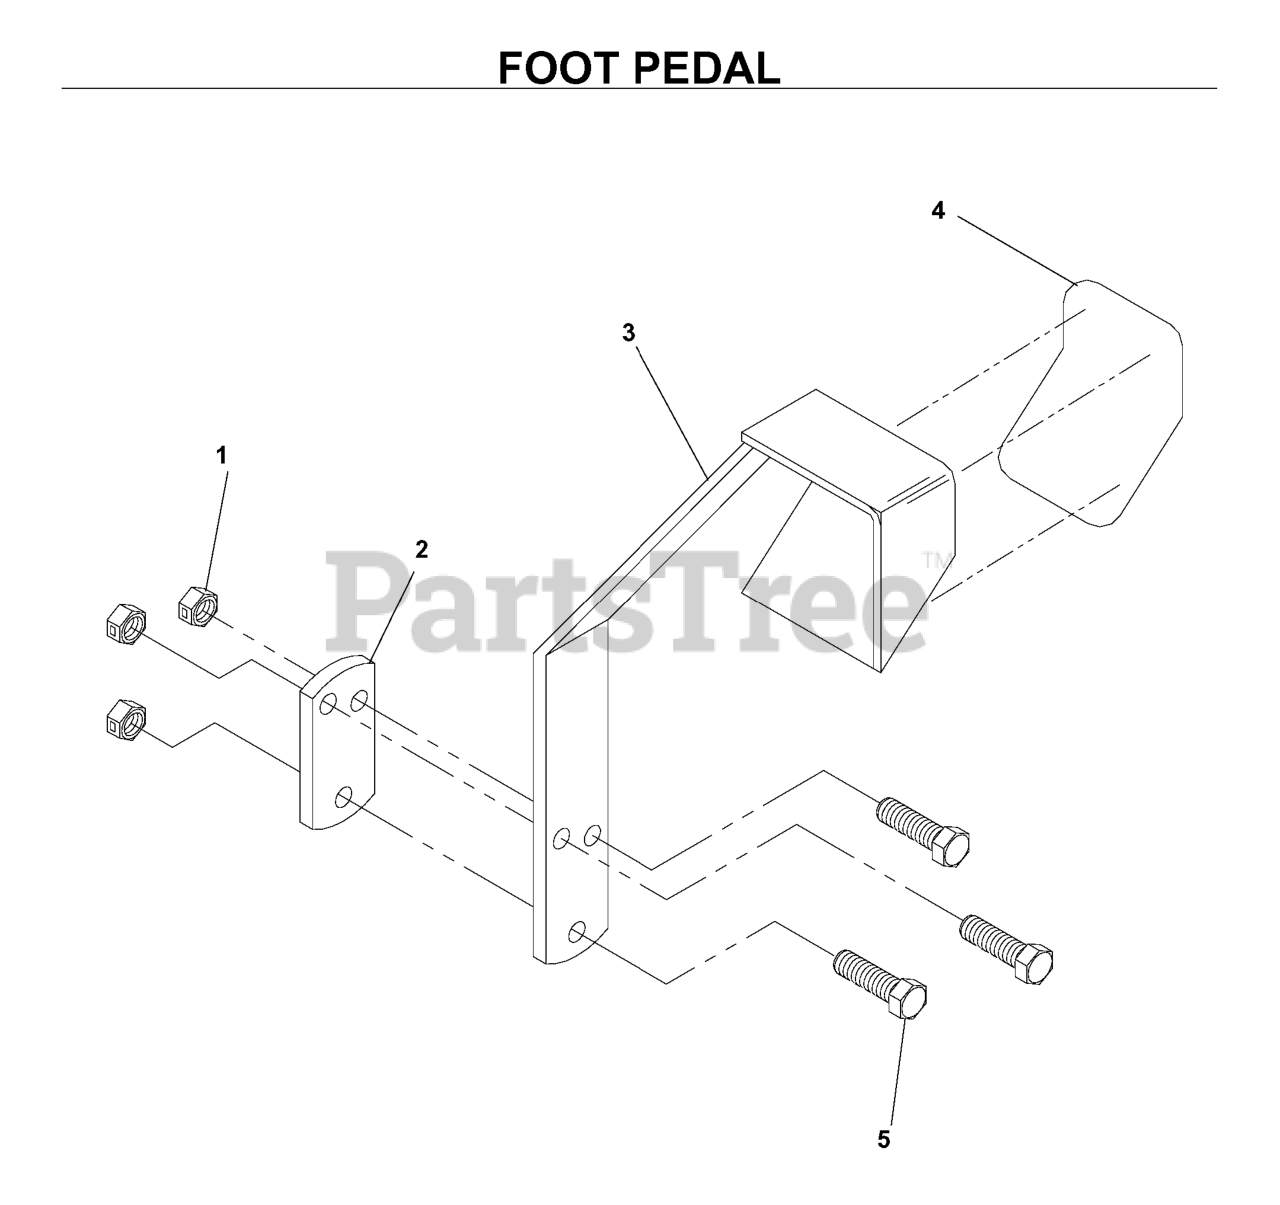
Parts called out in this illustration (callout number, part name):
1	NUT 3/8-16 NYLOC
2	TIGHTENING PLATE BLK
3	LIFT PEDAL BLK
4	ANTI-SKID PAD
5	HCS 3/8C X 1 1/2
